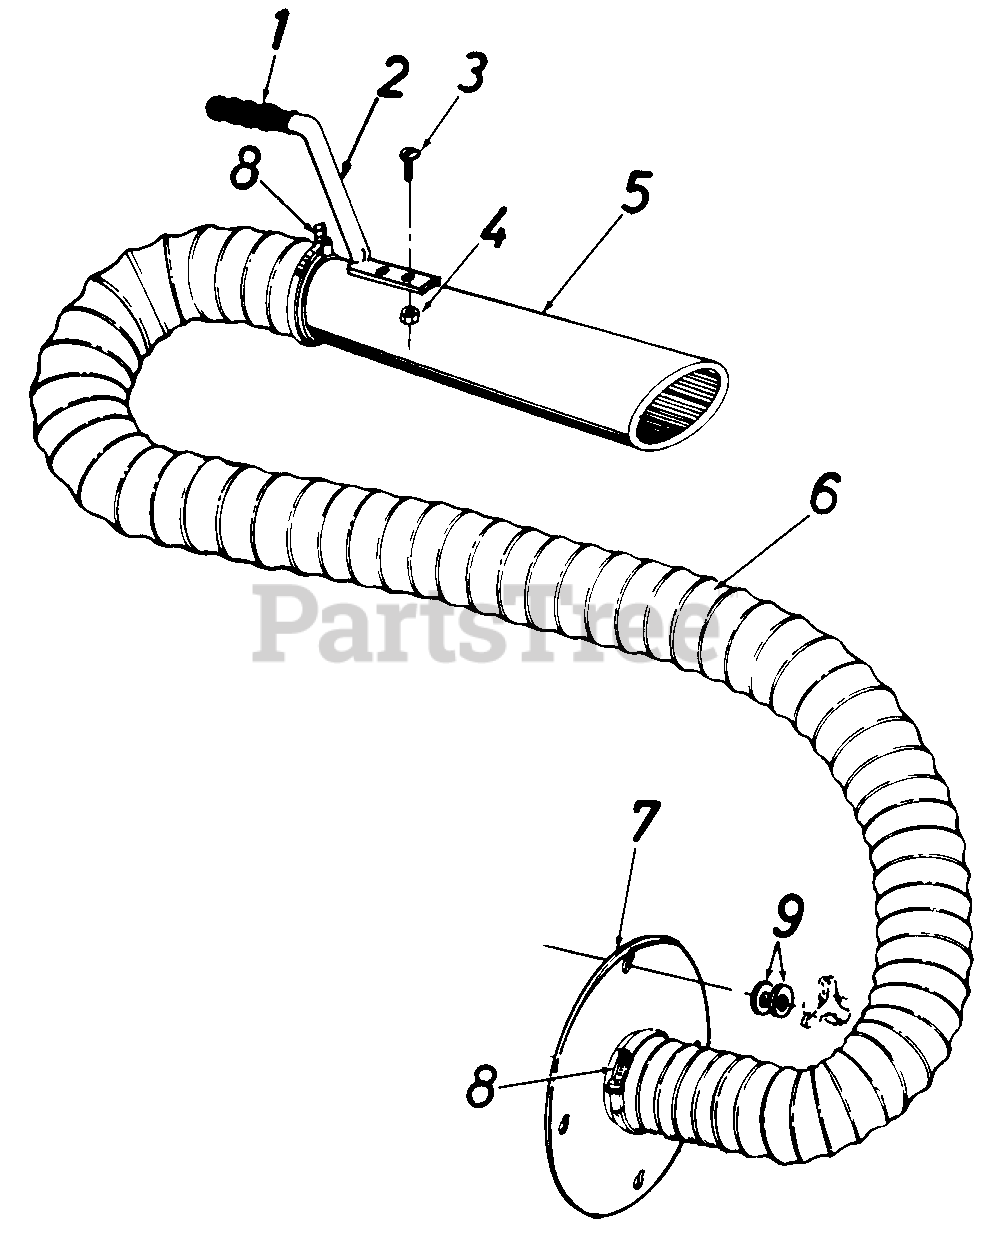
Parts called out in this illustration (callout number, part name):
1	Handle Grip
3	Truss Sems Scr 10-24 x 1/2" Lg
4	Hex Nut 10-24 Thd.
5	Hose Nozzle
6	Flexible Hose 4" Dia. x 10' Lg.
9	Flat Washer 34 I.D. x 1.12 O.D.
